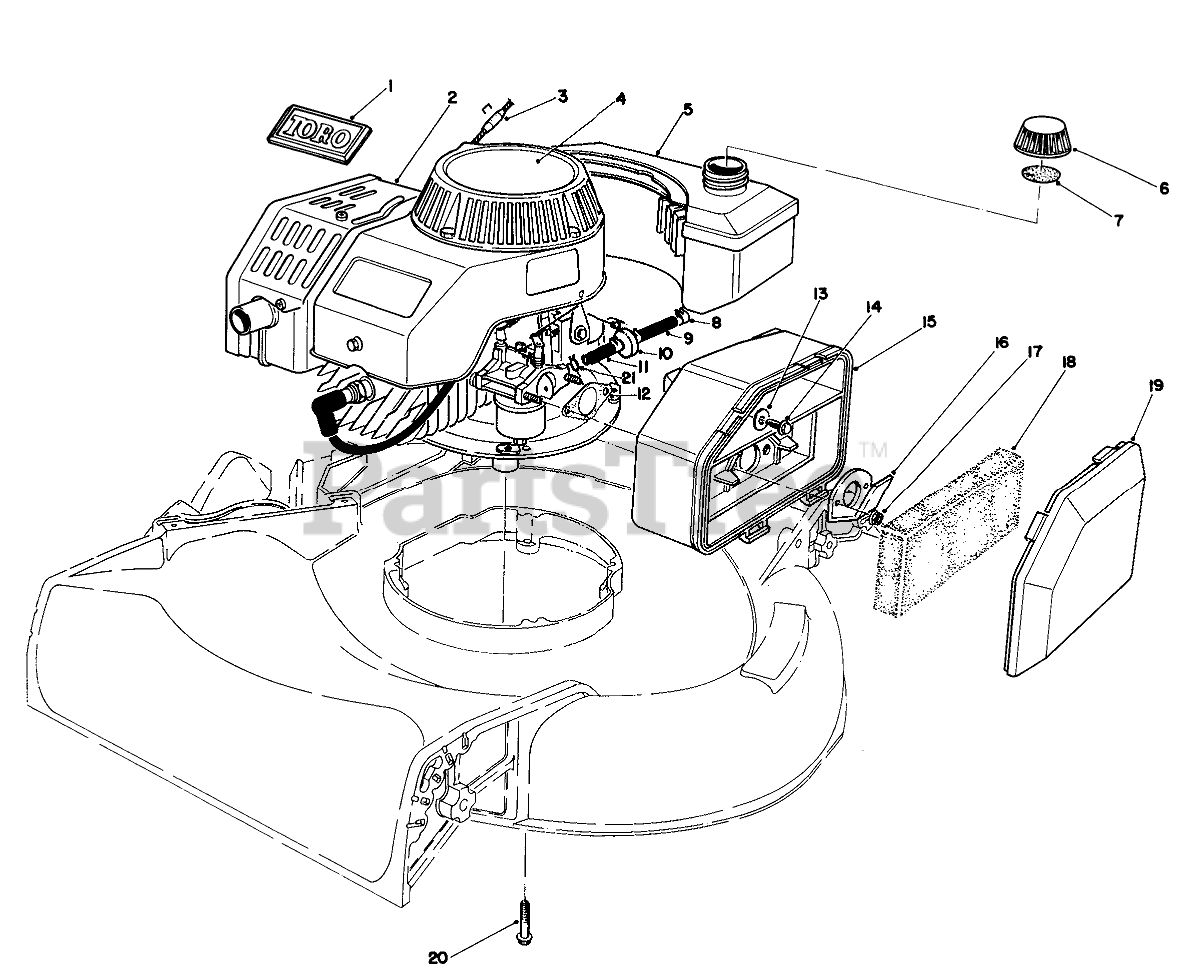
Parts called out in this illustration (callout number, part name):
1	TORO LOGO PLT
2	Engine
3	STOP-ROPE
4	DECAL
5	Fuel Tank Assembly
6	Gas Cap Assembly (Incl. Ref. #6)
7	GAS CAP GASKET
8	CLAMP-FUEL LINE
9	HOSE-FUEL
10	FILTER-FUEL
11	HOSE-FUEL
12	GASKET-AIR CLEANER
13	WASHER-FLAT
14	SCREW-HH
15	AIR CLEANER
16	SPIT BACK DEFLECTOR
17	NUT-LOCK
18	FILTER
19	AIR CLEANER COVER
20	FLG SCREW,3/8-16X2.000
21	CLAMP-HOSE
